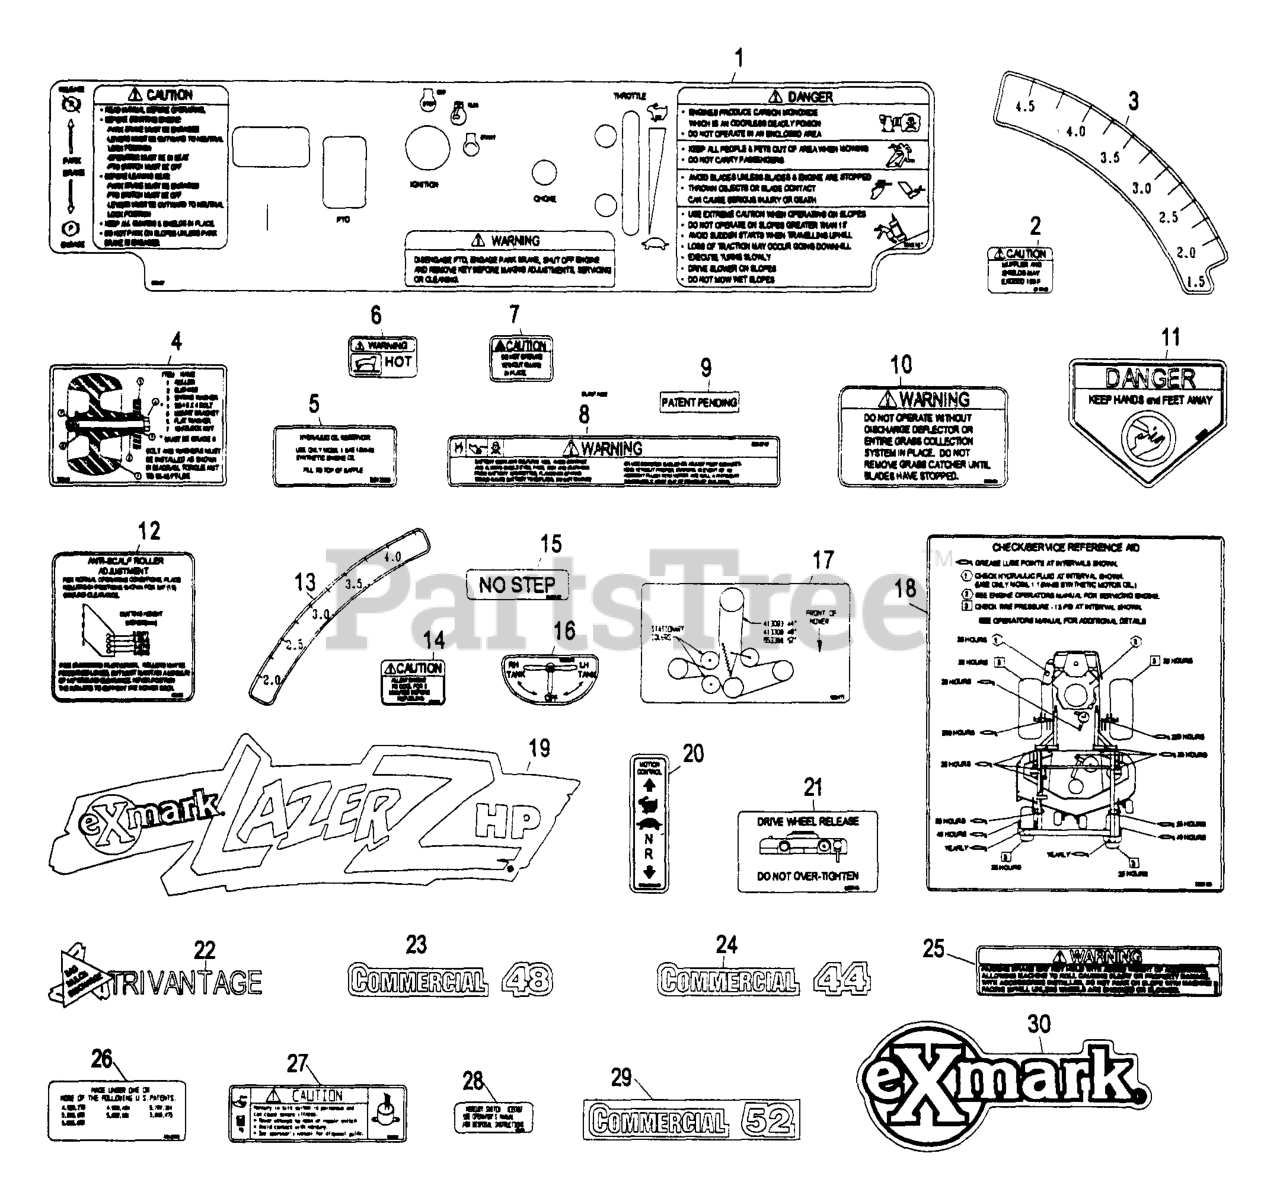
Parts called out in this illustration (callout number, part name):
3	DECAL-DECK HEIGHT, OUTER
4	DECAL,ROLLER MOUNTING
5	DECAL,HYD TANK
7	DECAL-GUARD
8	DECAL-BATTERY
9	Decal, Patent Pending
10	DECAL-WARNING, DISCHARGE
11	DECAL-DANGER
12	DECAL,ANTISCALP
13	DECAL-DECK HEIGHT, INNER
15	DECAL,NO STEP
21	DECAL,DRIVE RELEASE
23	DECAL,COMMERCIAL 48
24	DECAL,COMMERCIAL 44
25	DECAL,PARK BRAKE WARNING
27	DECAL,HAZARDOUS MATERIAL
28	DECAL-SWITCH, MERCURY
29	DECAL,COMMERCIAL 52
